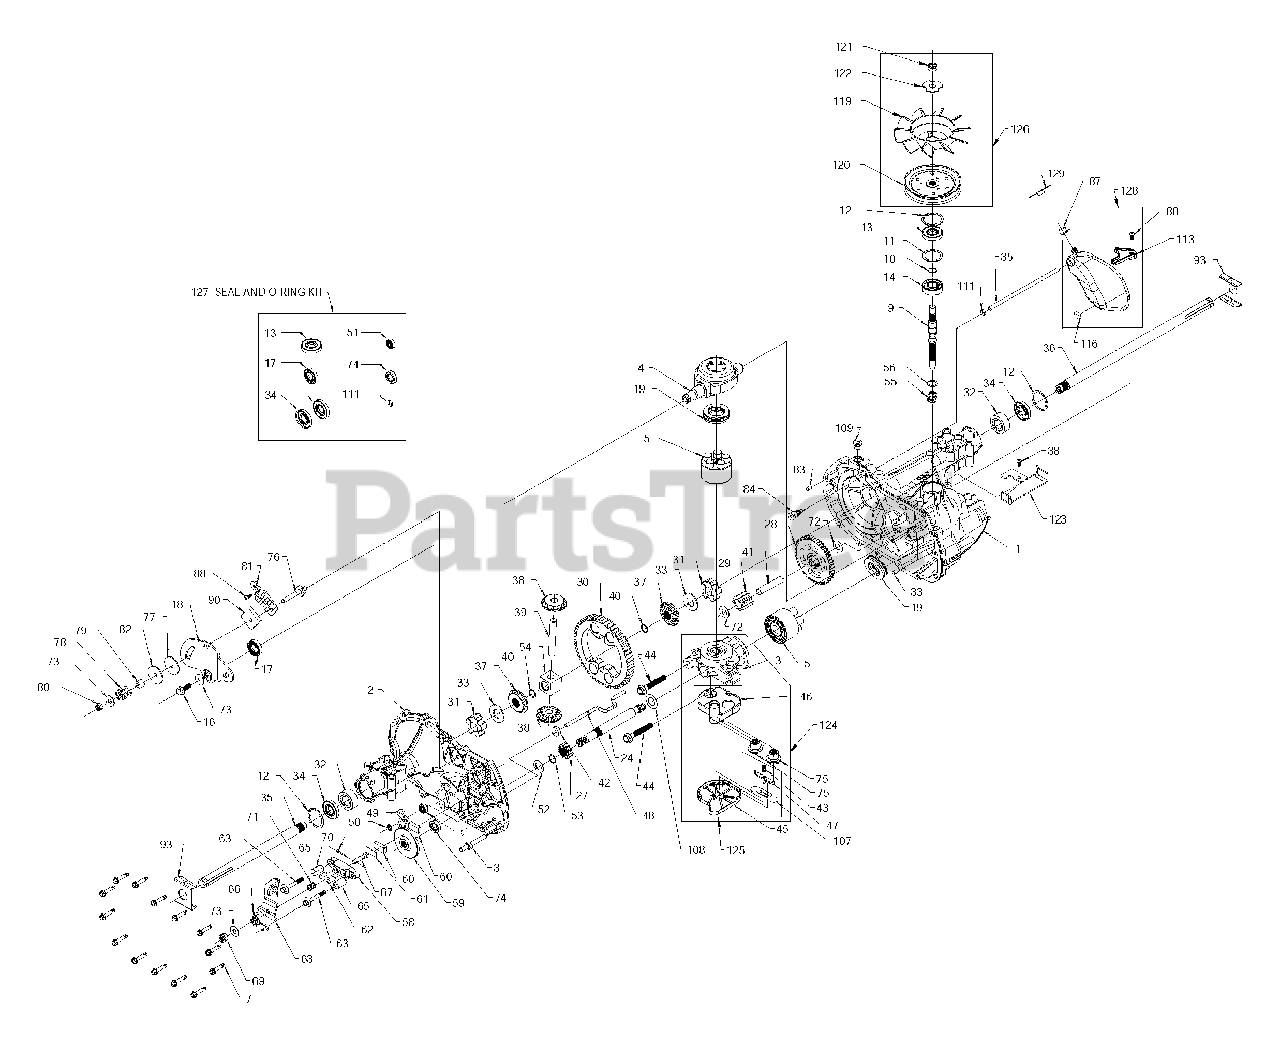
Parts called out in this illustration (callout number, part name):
1	MAIN HOUSING, ASSEMBLY
2	SIDE HOUSING, ASSEMBLY
3	CENTER SECTION, ASSEMBLY
4	SWASHPLATE, TRUNNION MACHINED
5	BLOCK - ASSEMBLY
7	HEX FLANGE SCREW 1/4-20 X 1.25
8	STUD, 5/16-24 HEX DOUBLE END
9	SHAFT, INPUT
10	RING - RETAINING
12	RING - RETAINING
14	BALL BRG 17MM ID X 40MM OD X 12MM
16	HEX FLANGE HEAD SCREW 5/16-24 X 0.75
18	ARM, CONTROL
19	BEARING, 30X52X13 THRUST
24	SHAFT, MOTOR
28	10T/48T GEAR
29	GEAR, 10T JACKSHAFT
30	60T BULL GEAR
32	SLEEVE BEARING (OUTBOARD) .75 X 1.575 X .625
33	WASHER, 3/4 ID X 1-1/2 OD X .13 THK
34	LIP SEAL AXLE SEAL
35	SHAFT, AXLE .75 x 11.39 (KEY, R.H.)
36	SHAFT, AXLE .75 X 16.99 (KEY, L.H.)
37	MITER GEAR (SPLINED)
38	MITER GEAR 15T (0.5 ID)
39	SHAFT
40	RING, SPIRAL RETAINING
41	PIN, JACKSHAFT
42	MAGNET, RING
43	SPRING, BYPASS
45	BOTTOM, FILTER
46	BASE, FILTER W/POPPET
47	ACTUATOR, BYPASS
48	ROD, BYPASS ACTUATOR
49	ARM, BYPASS
50	RETAINING RING .250 EXTERNAL
51	SEAL, LIP .741 X .250 x .250 TC
52	FLAT WASHER, 5/8 ID X 1.0 OD X .05 THK
53	RETAINING RING
54	BEARING, CENTER BLOCK
55	SPRING - HELICAL COMPRESSION
59	ROTOR, BRAKE
62	BRAKE ACTUATING PIN
63	HFHCS 1/4-20 X 2 W/PATCH
66	SPRING, BRAKE ARM BIAS
67	SQ.HD.BOLT 5/16-24- RIBBED
68	ARM, BRAKE
69	SLOTTED HEX NUT 5/16-24
70	COTTER PIN 3/32 X 3/4
71	SPRING, COMPRESSION
73	FLAT - WASHER 11/32 I.D. X 7/8 O.D
75	CHECK PLUG ASSEMBLY, .027, WASHER
76	STUD, 5/16-24 FRICTION PACK
77	PUCK, .330 X 1.50 X .0975
78	SPRING, HELICAL COMP
80	HEX LOCK NUT 5/16-24 UNJF
81	WEDGE, FRICTION PACK
82	WASHER .316 X 1.50 X .1046 (PLATED)
83	PIN, STANDARD HEADLESS
84	FITTING, 5/16 SAE 5/32 TUBE
85	HOSE, EXPANSION TANK
87	CAP, VENT
88	BOLT, SELF TAPPING 10-32 X 1/2
90	PUCK, INNER WEDGE
93	SPRING CLIP - HOUSING THRUST
107	DEFLECTOR
108	WASHER, .71 X 1.16 X .030 THK
109	PLUG, SAE #6
111	O-RING .07 X .301 ID
113	BRACKET,SUPPORT EXPANSION TANK
116	SILICON SPONGE
119	FAN 6" 10 BLADE
120	PULLEY 3.86
121	NUT, HEX LOCK 1/2-20 (NYLON INSERT)
122	WASHER, OD SLOTTED .53 X 1.63 X .06
123	BELT KEEPER
126	KIT, FAN/PULLEY (Incl Ref No 13, 17, 34, 51, 74 & 111)
127	SEAL - O-RING KIT (Incl Ref No 13, 17, 34, 51, 74 & 111)
128	KIT, EXPANSION TANK (Incl Ref No 87, 88, 113 & 116)
129	CAP, EXPANSION TANK SHIPPING
